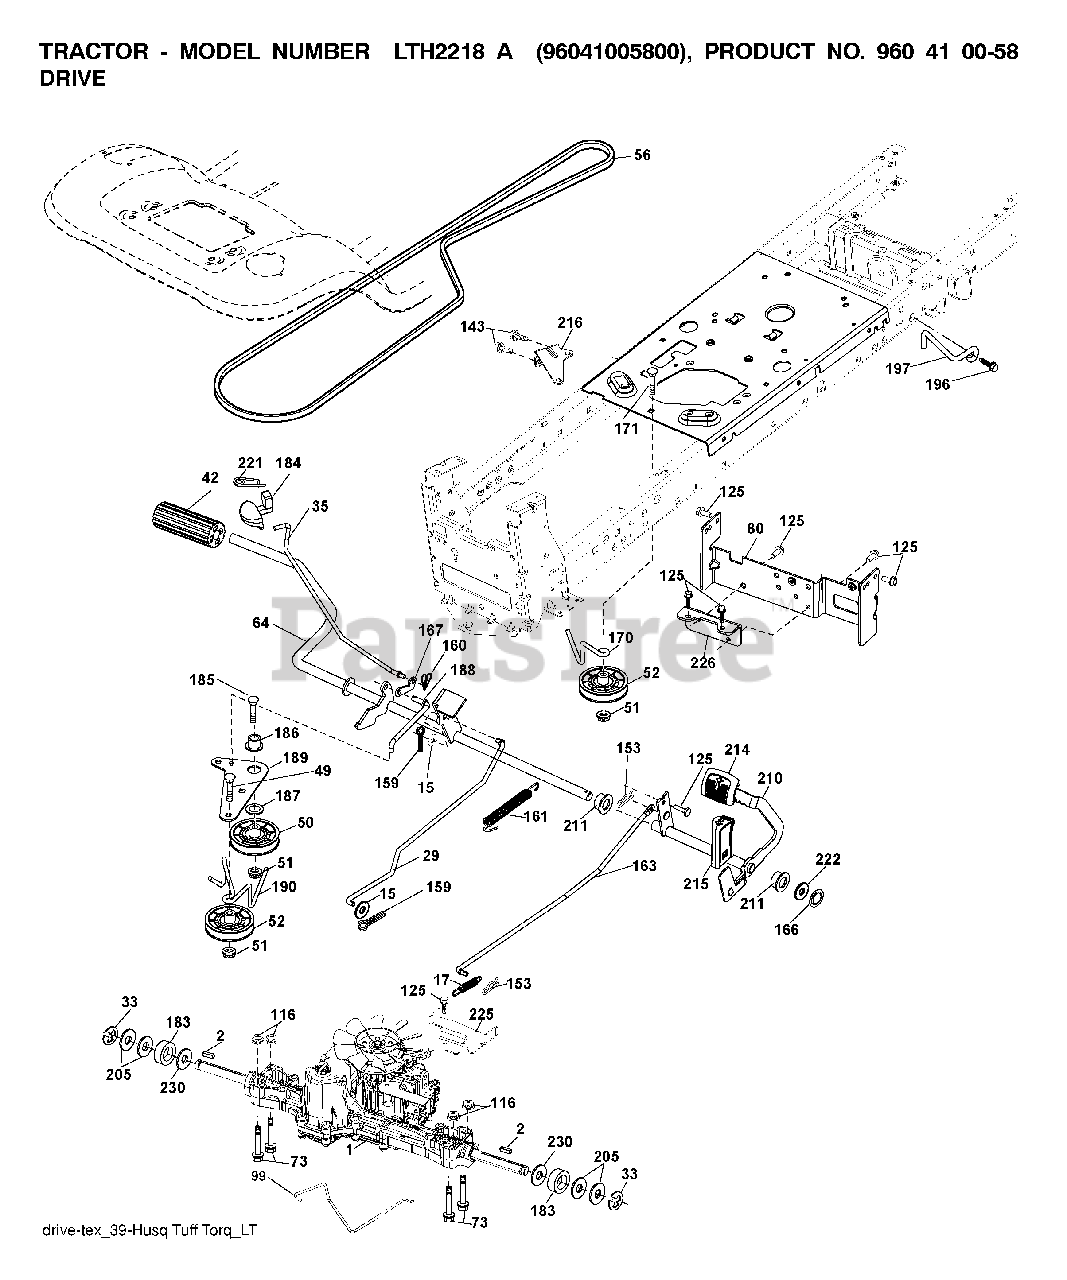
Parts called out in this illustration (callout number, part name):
2	SQUARE KEY
17	SPRING.BRAKE.K46
29	ROD.BRAKE.K46
33	E-RING LT
35	ROD.BRAKE.PARKING.LT.T
42	PEDAL COVER T
49	BOLT
50	IDLER.FLAT.910.OFFSET
51	NUT LOCK FLG 3/8-16 UNC
52	IDLER.V-GROOVE.910.OFFSET
64	SHAFT.ASM.PEDAL.BRK.CNTR
73	BOLT HEX 5/16-18 GR 5
80	STRAP TORQUE
99	ROD ASM BYPASS
116	NUT LOCK HEX FLANGE 5/16-18
125	SCREW
153	RETAINER M
159	COTTER PIN
160	RETAINER CLIP
161	SPRING.RETURN.CLUTCH.2006
163	ROD.CONTROL.PEDAL.K46
166	NUT.PUSH.625.2006
167	LATCH.BRAKE.SPRING
170	KEEPER.V-IDLER.CENTER.
171	BOLT
183	SPACER AXLE
184	HANDLE PARKING BRAKE
186	SPACER.RETAINER
187	WASHER 12/32X2X10GA
188	LINK.CLUTCH.GROUND.DRIVE
189	BELLCRANK.GROUND.DRIVE.TEX.
190	KEEPER.BELLCRANK.DRIVE
196	SCREW 3/8-16X1
197	LINK.CLUTCH.ANIT-ROTAT
210	ROCKER.ASM.PEDAL.CONTR
211	BEARING.NYLON
214	PEDAL.FORWARD.TEX.GT.4
215	PEDAL.REVERSE.TEX.GT.4
216	BRACKET.PULLEY.IDLER.W/TEX
221	RETAINER.SPRING.CLIP.H
222	WASHER 21/32 X 1-1/4 X 10 GA.
225	KEEPER.BELT.TRANSAXLE.K46
226	BRACKET.MOUNT.TORQUE.K46.TLT
230	WASHER.HARDENED
